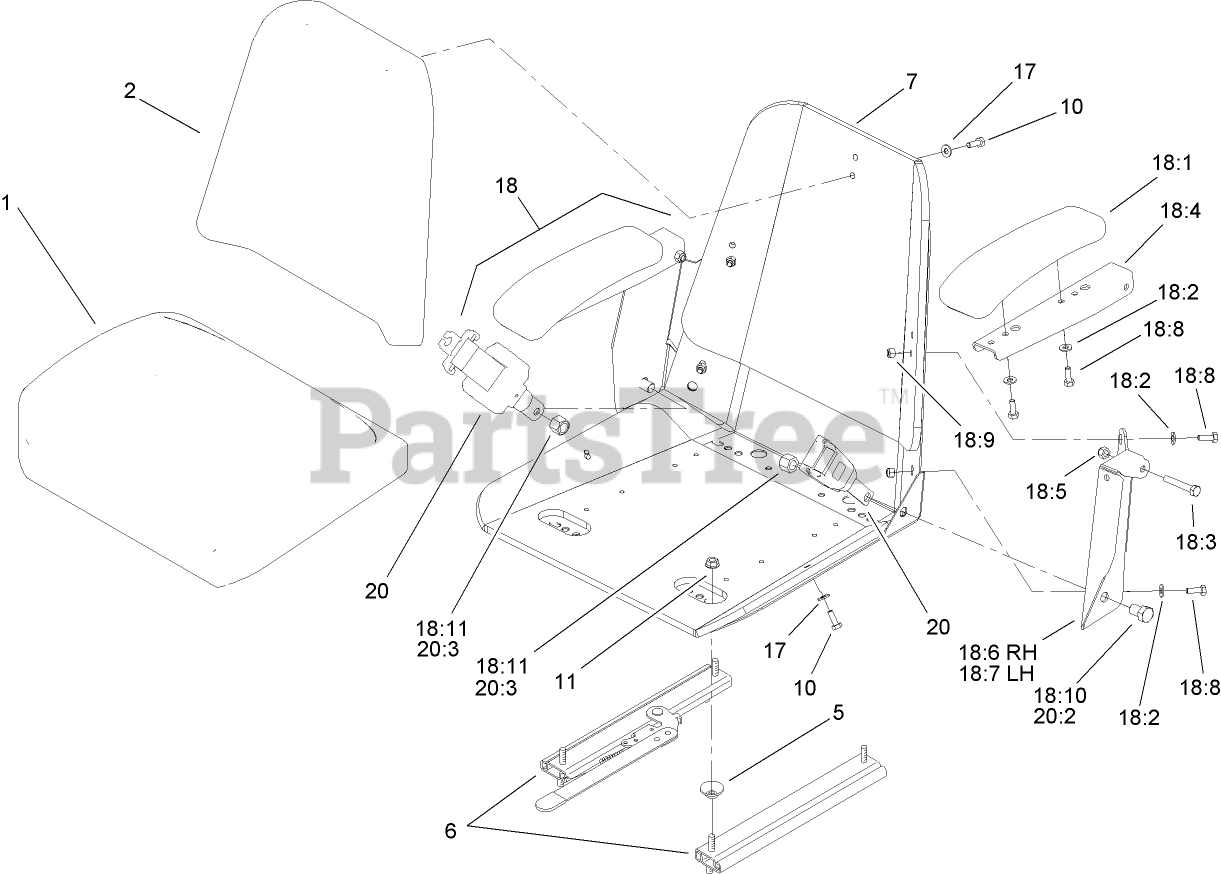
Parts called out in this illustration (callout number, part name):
1	CUSHION-SEAT, BOTTOM
2	CUSHION-SEAT, BACK
5	SPACER-TRACK
6	TRACK-SEAT
7	FRAME-SEAT
10	SCREW-HH
11	NUT-HF
17	WASHER-FLAT
18	ARMREST KIT
18:1	CUSHION-ARMREST
18:2	WASHER-FLAT
18:3	SCREW-HH
18:4	CHANNEL-ARMREST
18:5	NUT-HEX, SIDE DEFORM
18:6	Bracket-Armrest, RH
18:7	Bracket-Armrest, LH
18:8	SCREW-HH
18:9	NUT-LOCK, NI
18:10	SCREW-HH
18:11	NUT-LOCK, NI
20	RETRACTABLE SEATBELT KIT
20:2	SCREW-HH
20:3	NUT-LOCK
